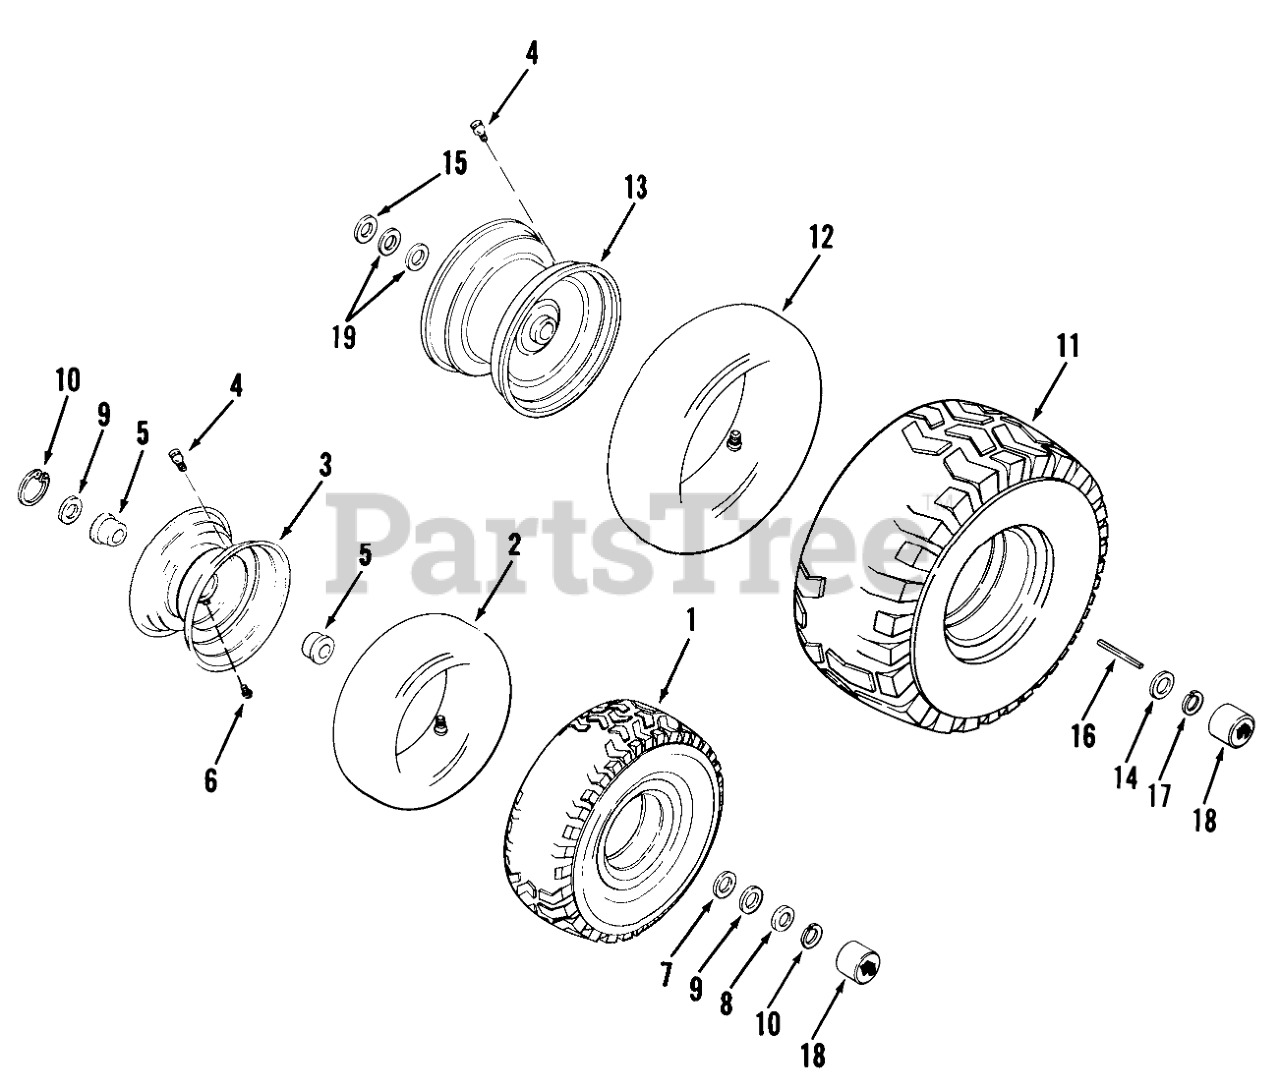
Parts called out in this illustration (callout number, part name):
1	TIRE
2	Front Tube-Service Only
2	TUBE-TIRE 11X4.00-5
3	ASSY-WHEEL(COMPLETE)
3	Front Wheel
4	VALVE
5	FLANGE BEARING
6	Zerk
7	WASHER-SHIM
9	WASHER
10	Snap Ring
11	TIRE15 X 6.00-6
12	Tube (Service Only)
13	Wheel-Rear
15	WASHER
16	SQ KEY
17	Snap Ring
18	HUB CAP
